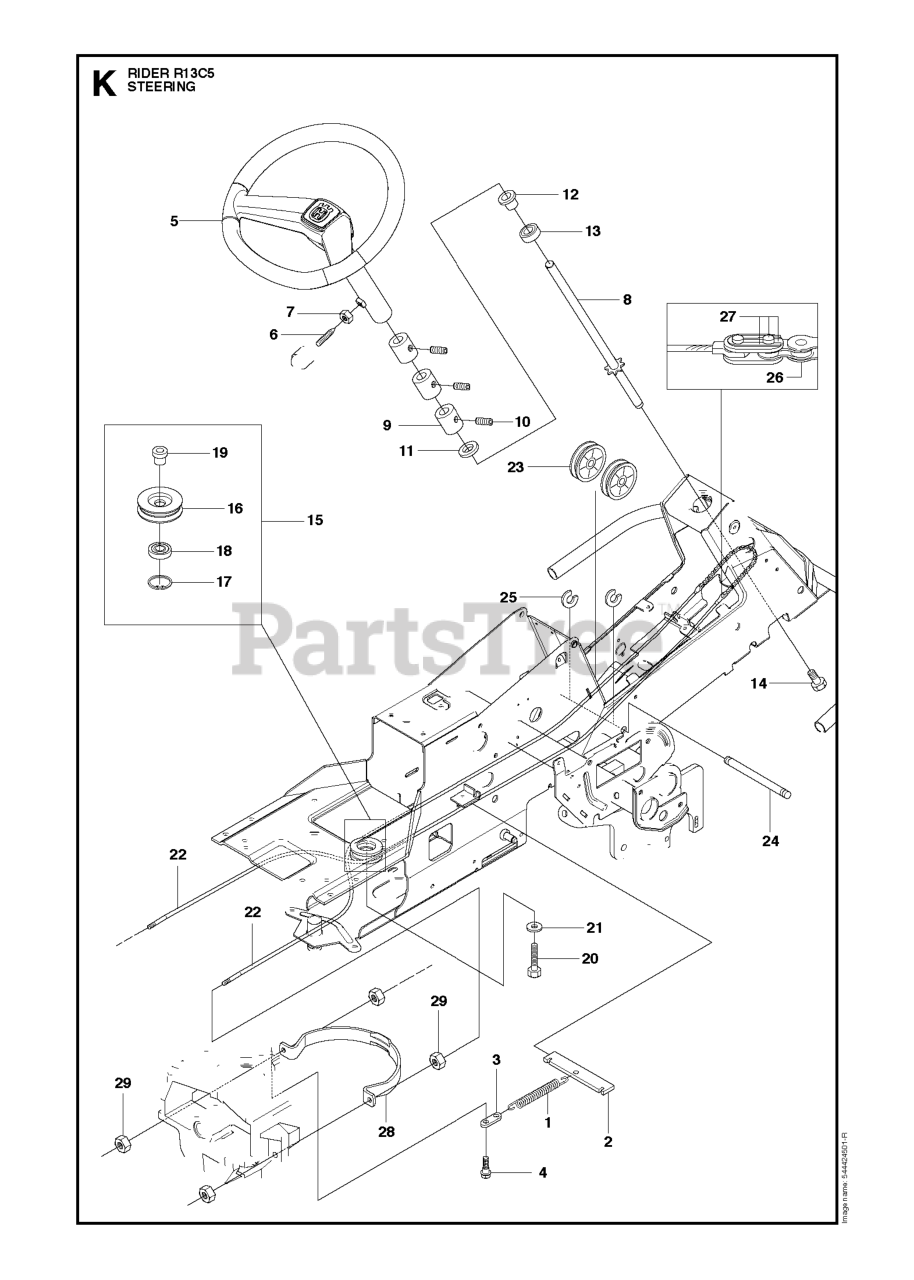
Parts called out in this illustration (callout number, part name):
2	SPRING BRACKET
5	STEERING WHEEL
7	NUT
8	STEERING ROD
9	SPACER
13	BALL BEARING 6004-2RS1
17	CIRCLIP SGH 47
18	BALL-BEARING 6204-2RS
22	RP STEERING CABLE COMPLETE
24	SHAFT
25	RETAINING RING
26	STEERING CHAIN
28	WIRE GUIDE
29	NUT
